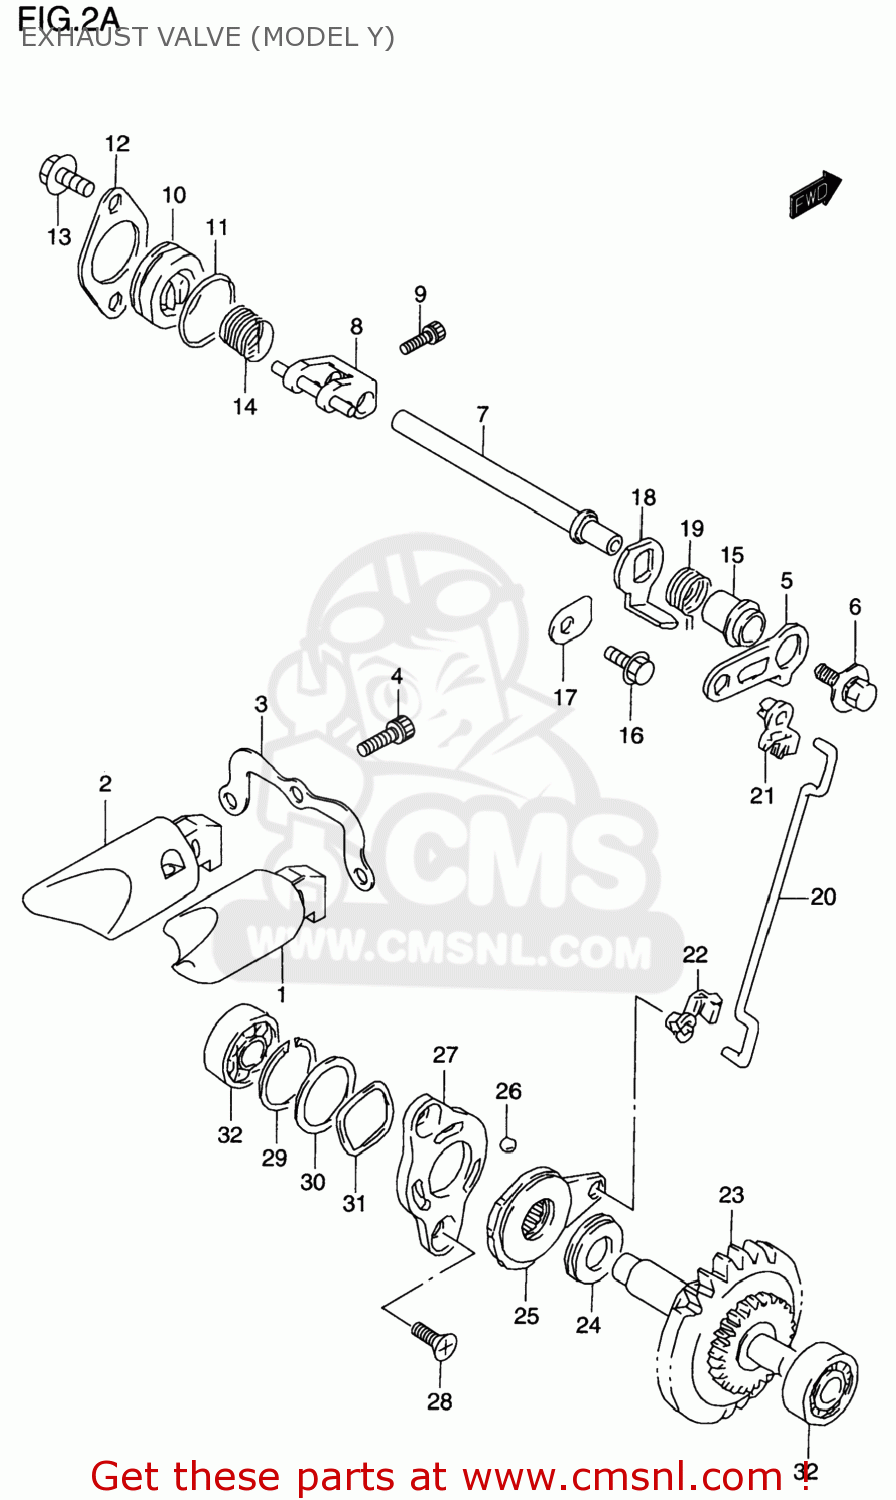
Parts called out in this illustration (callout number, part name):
1	VALVE,EXHAUST,RIGHT
2	VALVE,EXHAUST,LEFT
3	PLATE,EXHAUST VALVE
4	BOLT
5	LEVER,EXHAUST VALVE NO.1
6	BOLT(5X12)
7	SHAFT,EXHAUST VALVE
8	ARM,EXHAUST VALVE SHAFT
9	BOLT(4X8)
10	CAP,EXHAUST VALVE
11	O RING(D:1.9,ID:22.6)
12	RETAINER,EXHAUST VALVE
13	BOLT
14	SPRING,EXHAUST VALVE
15	SPACER,EXHAUST VALVE
16	BOLT
17	RETAINER
18	LEVER,EXHAUST VALVE NO.2
19	SPRING
20	ROD,EXHAUST VALVE
21	BUSH,EXHAUST VALVE ROD NO.1
22	BUSH,EXHAUST VALVE ROD NO.2
23	GOVERNOR ASSY,EXHAUST VALVE
24	BEARING(10X22X2.8)
25	ACTUATOR,EXHAUST VALVE
26	BALL
27	STARTER,EXHAUST VALVE ACTUATOR
28	SCREW(5X10)
29	CIRCLIP
30	SHIM(19.1X25X0.3)
31	WASHER
32	BEARING(8X22X7)
